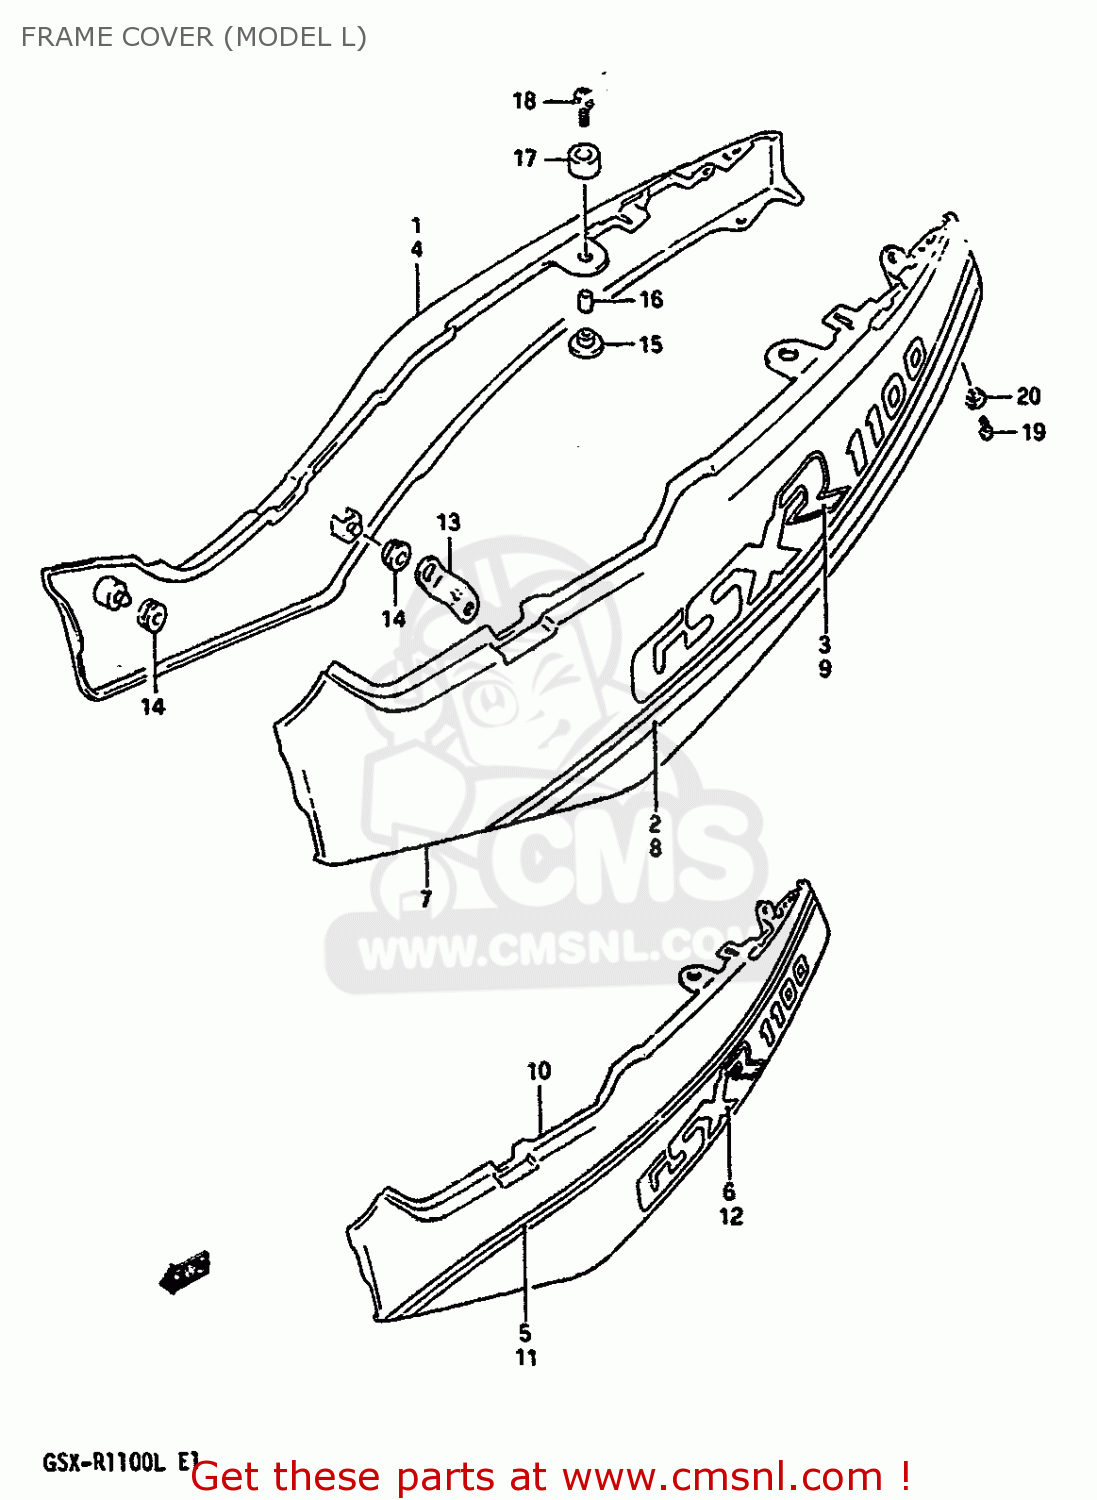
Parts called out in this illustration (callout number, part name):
1	COVER,FRAME RH
2	TAPE,FRAME COVER RH
3	EMBLEM,FRAME COVER
4	COVER,FRAME,RIGHT
5	TAPE,FRAME COVER STRIPE
6	EMBLEM,FRAME COVER
7	COVER,FRAME LH
8	TAPE,LH
9	EMBLEM,FRAME COVER
10	COVER,FRAME,LEFT
11	TAPE,FRAME COVER STRIPE
12	EMBLEM,FRAME COVER
13	BRACKET,FRAME COVER
14	CUSHION
15	CUSHION,FRAME COVER LWR
16	SPACER
17	CUSHION,TAIL COVER UPR
18	SCREW(6X30)
19	SCREW, FRONT & REAR
20	WASHER(5.2X14X1.5)
21	CUSHION,TAIL COVER UPR
22	SCREW
23	WASHER
24	SCREW, FRONT & REAR
25	WASHER(5.2X14X1.5)
